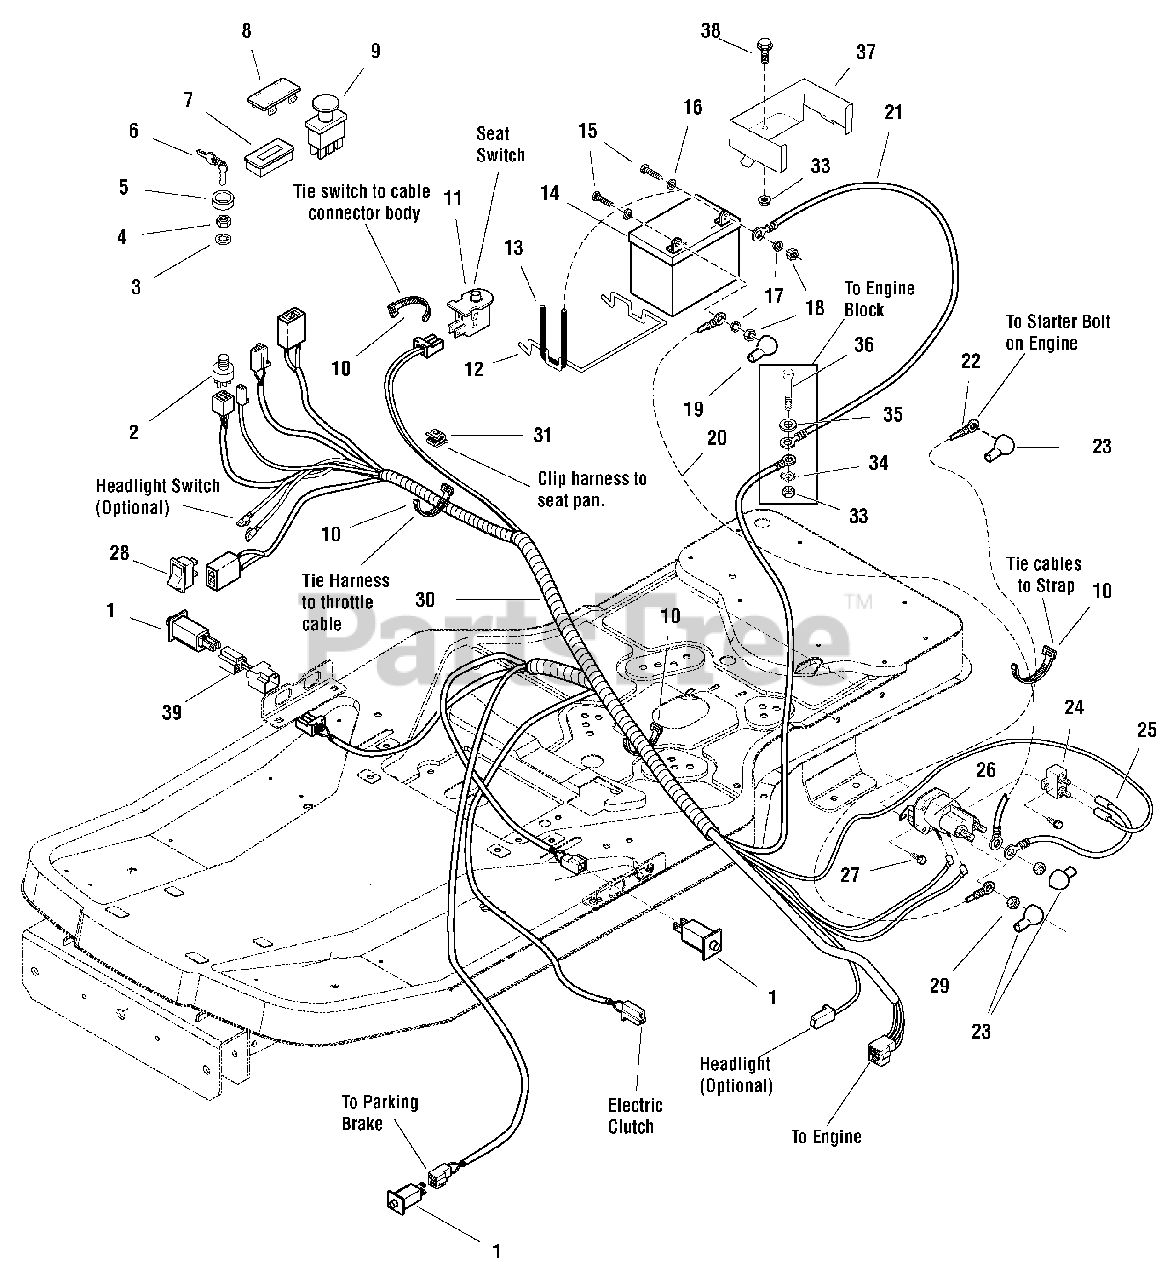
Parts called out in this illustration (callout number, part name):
1	SWITCH, Push Button (NO/NC)
2	SWITCH ASSEMBLY, Ignition
3	LOCKWASHER, Internal Tooth 5/8" Thin
4	NUT, 5/8-32 Hex Flange (Ignition Switch Die Cast)
5	COVER, Ignition Switch
6	KEYS, (set of two, one coated)
6	KEYS, Blister Pk (KIDS+MWRS DON'T MIX) (set of two, one coated)
7	HOUR METER, No Alarms
8	PLUG, Hole (Black Plastic)
9	SWITCH, PTO, Push/Pull Symbols
10	TIE, Self Locking, .184 Wide 7.31 Long
11	SWITCH, Push Button (NC) (Gray)
12	BRACE, Battery, .19 Dia. Wire
13	STRAP, Black Rubber, .19 Square 7.88 O.D. Battery
14	BATTERY, 12 Volt, 230 CCA
15	SCREW, 1/4-20 x 3/4" Hex Head Cap, GR5
16	WASHER, 1/4, .27 I.D. x .62 O.D. x .05 Thick
17	WASHER, 1/4" Spring Lock
18	NUT, 1/4-20 Hex
19	BOOT, Insulator, Red PVC Warning
20	CABLE, #6 x 10" Long, Red, Battery Positive, Two-Ring Terminals
20	CABLE, #6 x 34" Long, Red, Battery Positive, Two-Ring Terminals
21	CABLE, #6 x 26" Long, Black, Two-Ring Terminals
22	CABLE, #6 x 15" Long, Red, Two-Ring Terminals
23	COVER, Terminal Red PVC
24	BREAKER, Circuit 12 Volt 20 AMP
25	WIRE, 12 Gage
26	SOLENOID, Super Trombetta - 2 Terminal
27	SCREW, 1/4-20 x 1/2" Hex Washer Head Screw Black (Taptite)
28	SWITCH, Electric Height-of-Cut
29	NUT, 5/16-24 Hex Keps
30	HARNESS, Wiring
31	CLIP, Cable, .390 Wire Dia.
33	NUT, 5/16-18 Hex Flange Lock, Small - Black
34	WASHER, 3/8" External Tooth Lock
35	WASHER, .312 (.34 I.D. x.75 O.D.)
36	SCREW, 5/16-18 x 2" Hex Head Cap
37	BRACKET, Battery Hold Down
38	BOLT, 5/16-18 x 7/8" Hex Flange Lock
39	WIRING ASSEMBLY, Jumper All Conditions Shutdown (CE/Export)
